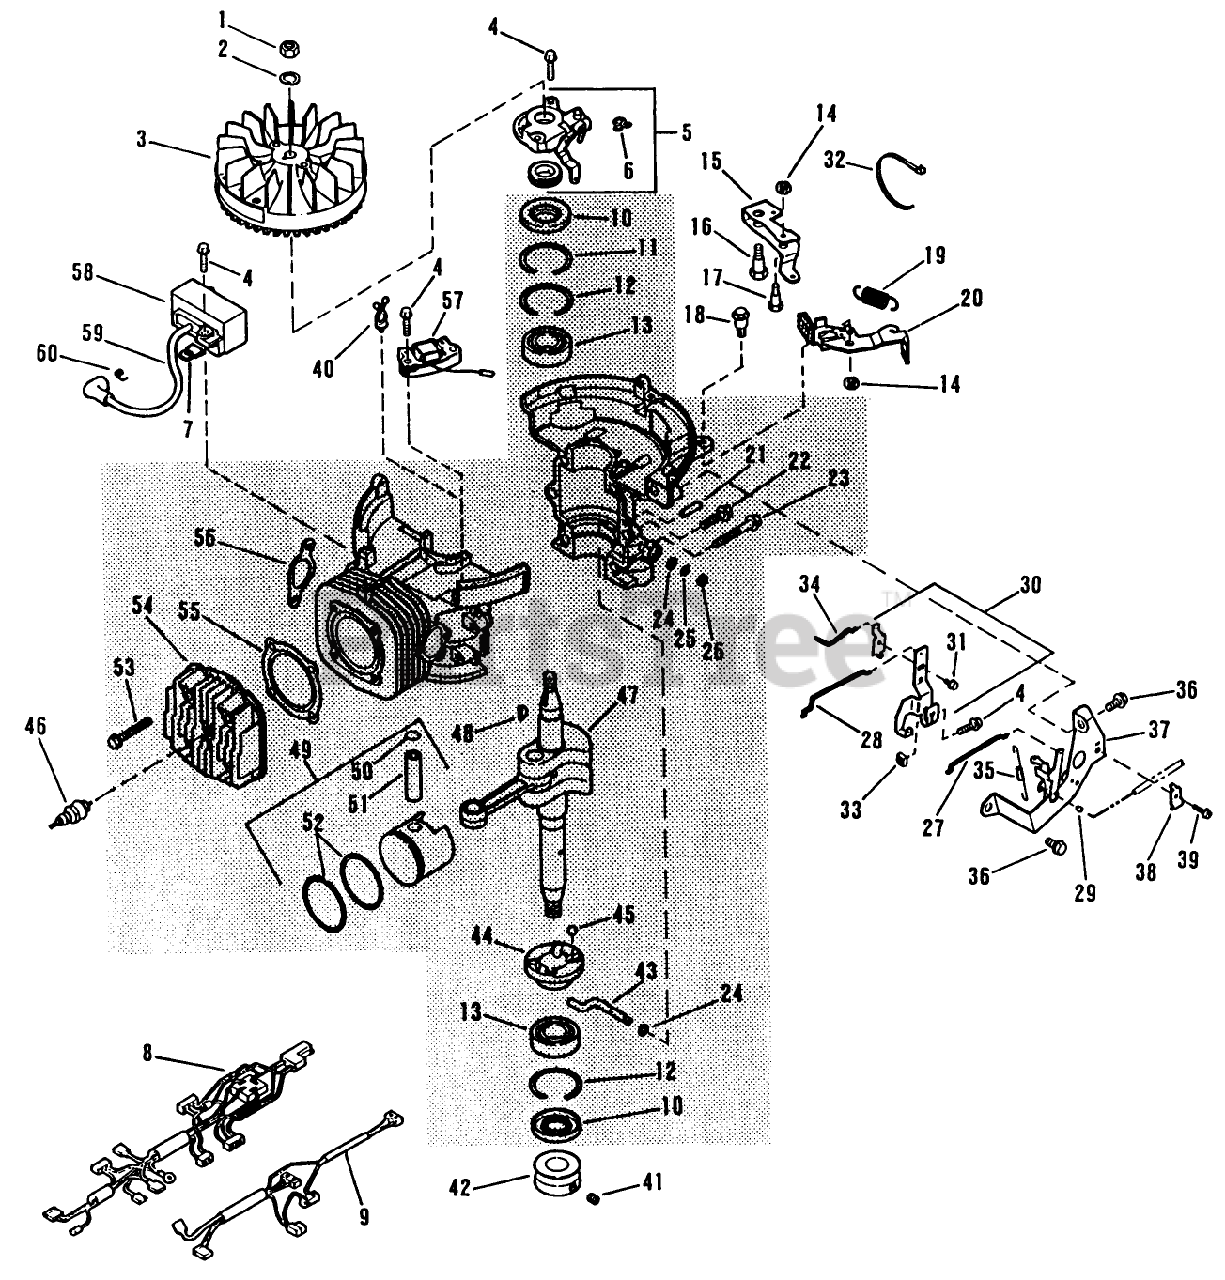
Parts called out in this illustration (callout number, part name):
1	NUT
3	FLYWHEEL AY SM
4	SCREW
8	WIRE HARNESS
10	SEAL - OIL SM
11	RING-RETAINER SM
13	BEARING-BALL SM
14	LOCKNUT E
15	ACT.BRAKE LVR. SM
16	SCREW-SHOULDER
19	SPRING-BRAKE
22	SCREW-H.W.HD. F
23	SCREW-HEX W.H. SM
25	RING-RETAINING
26	SEAL - OIL SM
28	ROD-THROTTLE SM
31	SCREW
35	SPRING-GOV. SM
37	GOVNR BRKT SM
40	WIRE TIE SM
42	PULLEY-ENGINE
48	KEY
52	RING SET S
53	SCREW
54	CYLINDER HEAD SM
56	GASKET - EXH SM
57	ALTERNATOR ASM
59	HI-TENS.LEAD
